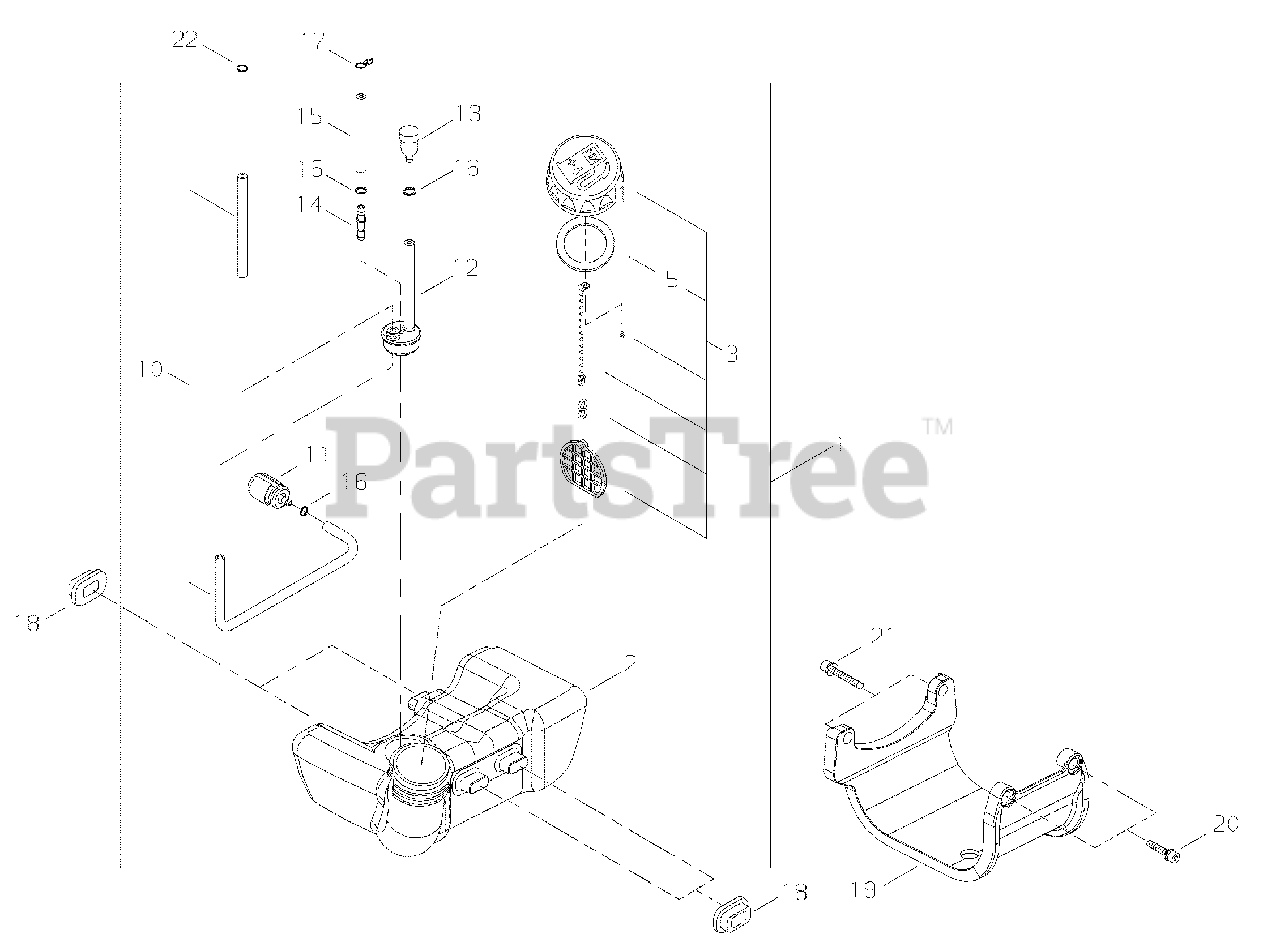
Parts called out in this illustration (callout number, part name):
1	TANK ASSY, FUEL
2	TANK, FUEL
3	CAP ASSY, FUEL
5	GASKET, FUEL CAP
10	PIPE, FUEL 3.3×6×215
11	FILTER, FUEL 125-528
12	GROMMET, FUEL W/VENT PIPE
13	VENT ASSY
14	CONNECTOR, PIPE
15	PIPE, FUEL RETURN
16	CLIP Ø6
17	CLIP, SPRING Ø5.2
18	CUSHION, FUEL TANK
19	GUARD, FUEL TANK
20	BOLT M5×18
21	BOLT M5×40
22	CLIP Ø6
